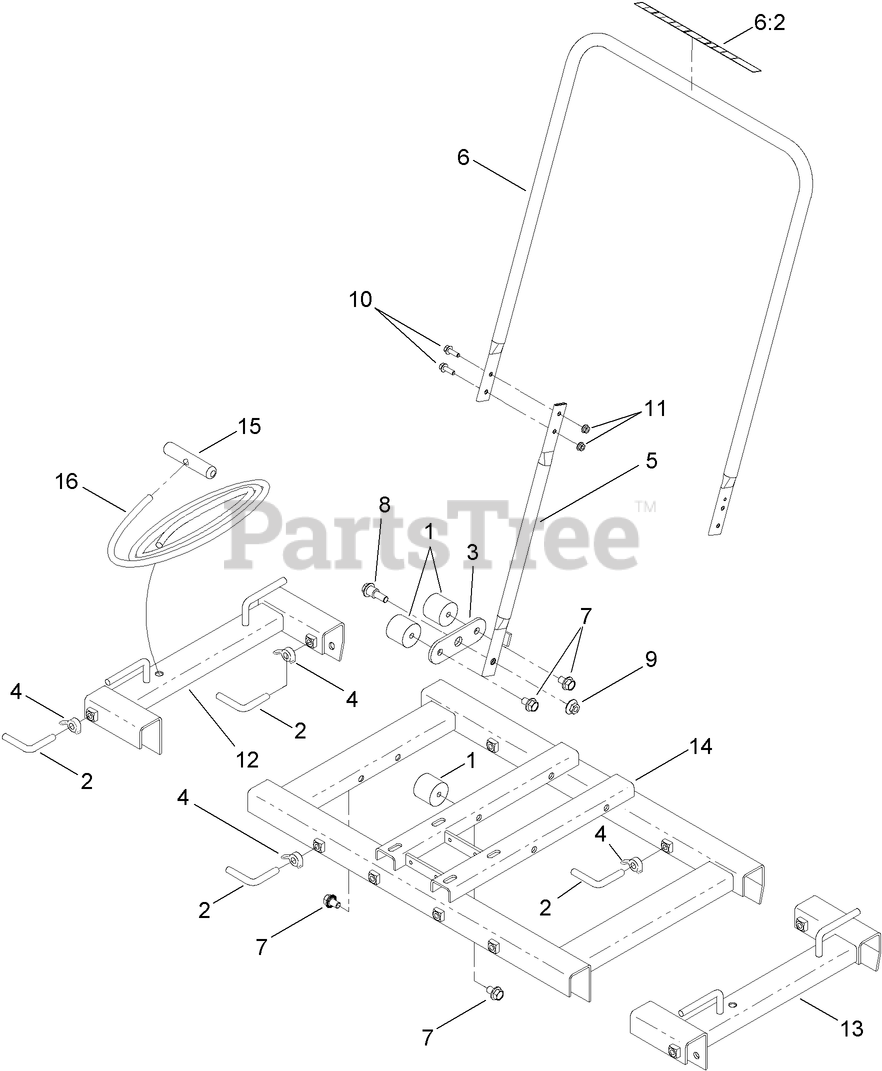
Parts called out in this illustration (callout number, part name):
1	MOUNT-SHOCK
2	L-BOLT
3	HANDLE-BRACKET
4	NUT-WING
5	TUBE-LOWER, HANDLE
6	UPPER HANDLE ASM
7	SCREW-HHF
8	SCREW-SHOULDER, HHF
9	NUT-HF
10	SCREW-HHF
11	NUT-FLANGE
12	SPREADER-LEFT
13	SPEADER-RIGHT
15	GRIP-PULL
16	ROPE-POLYPROP, 1/2 INCH
